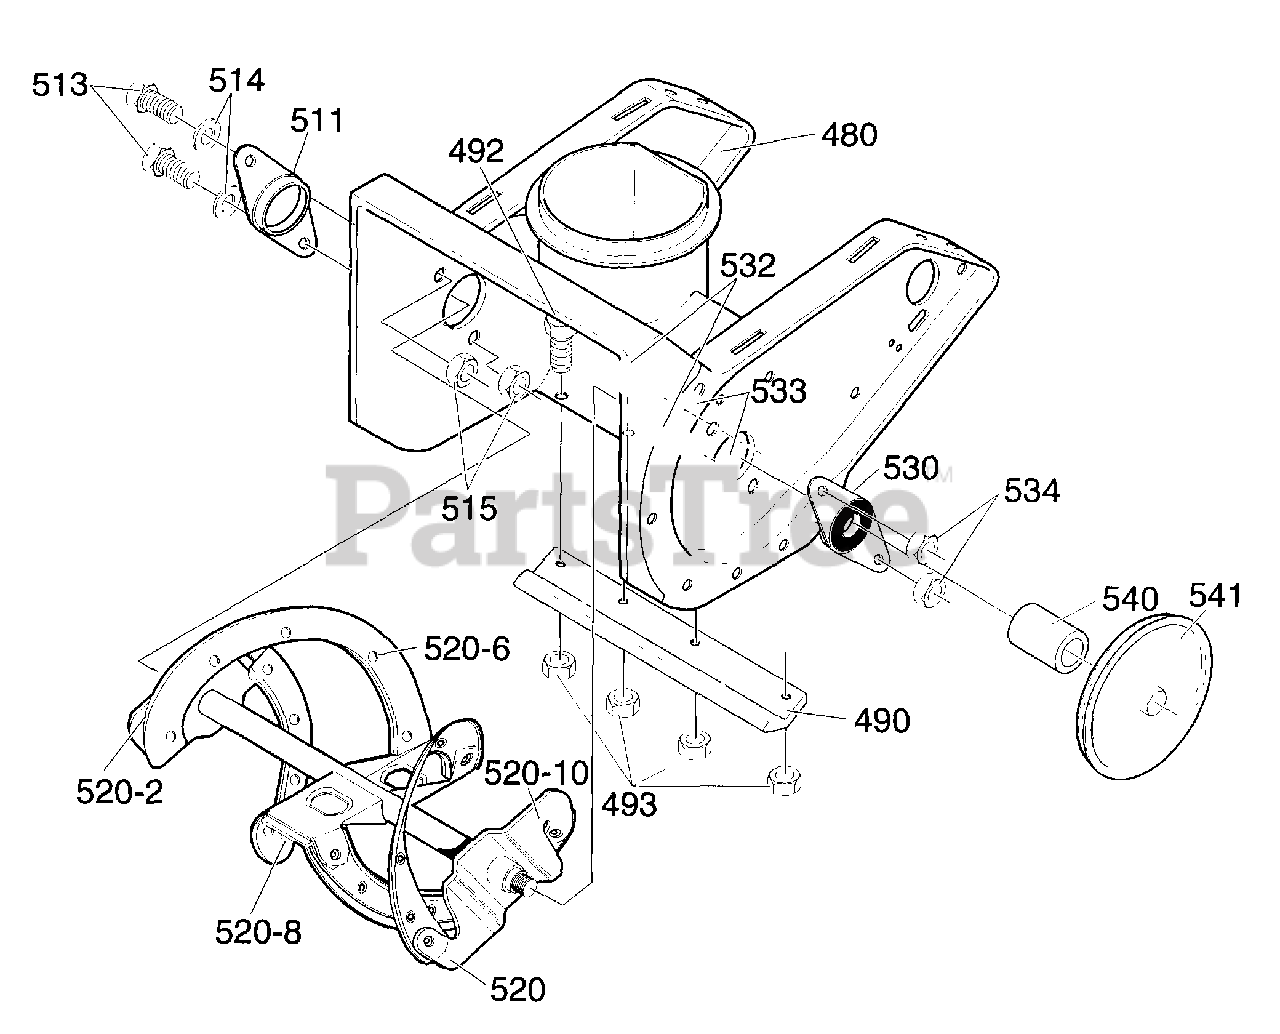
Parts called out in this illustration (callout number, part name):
480	HSNG, ASSY AUG 21"
490	BLADE, SCRAP 20.88 PLAST
492	SCREW, 1/4-20 X .63 SLTRMA
493	NUT, 1/4-20 WDFL MAC-LOCK
511	BRNG, FL .670 ID X 1.25 OD X .88
513	SCREW, 1/4-20 X .88 HHC
514	WASHER, FLAT .281 X .63 X .065
515	NUT, 1/4-20 WDFL MAC-LOCK
520	AUGER, ASSY COMP 2CY 21"
530	BRNG & PLATE, ASSY
532	SCREW, 1/4-20 X .75 HHC
533	WASHER, FLAT .281 X .63 X.065
534	NUT, 1/4-20 REGHEXCTRLK
540	SPACER, SLEV .640 X .88 X .732
541	PULLEY V3L 6.00 X .75 20 GA
